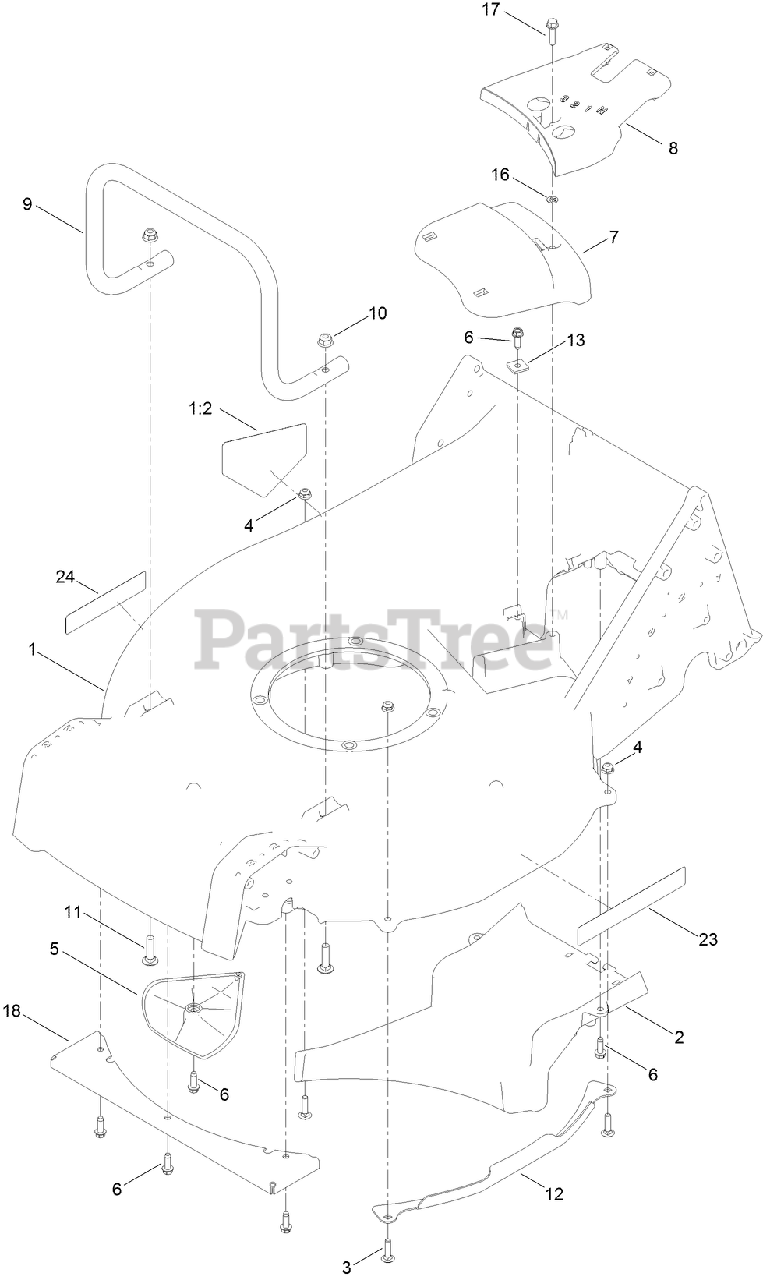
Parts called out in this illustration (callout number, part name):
1	HOUSING ASM
1:2	DECAL-DANGER
2	FLOOR-CHUTE
3	SCREW-CARR
4	NUT-HF
5	KICKER
6	SCREW-HWHTF
7	COVER-BELT, FRONT
8	COVER-BELT, REAR
9	GUARD-ENGINE
10	NUT-HF, NI
11	SCREW-CARR
12	GUARD-SIDE, DECK
13	CLAMP-CABLE
16	NUT-RETAINER
17	SCREW-HWHTF
18	GUARD-TOE, FRONT
23	DECAL-RECYCLER
